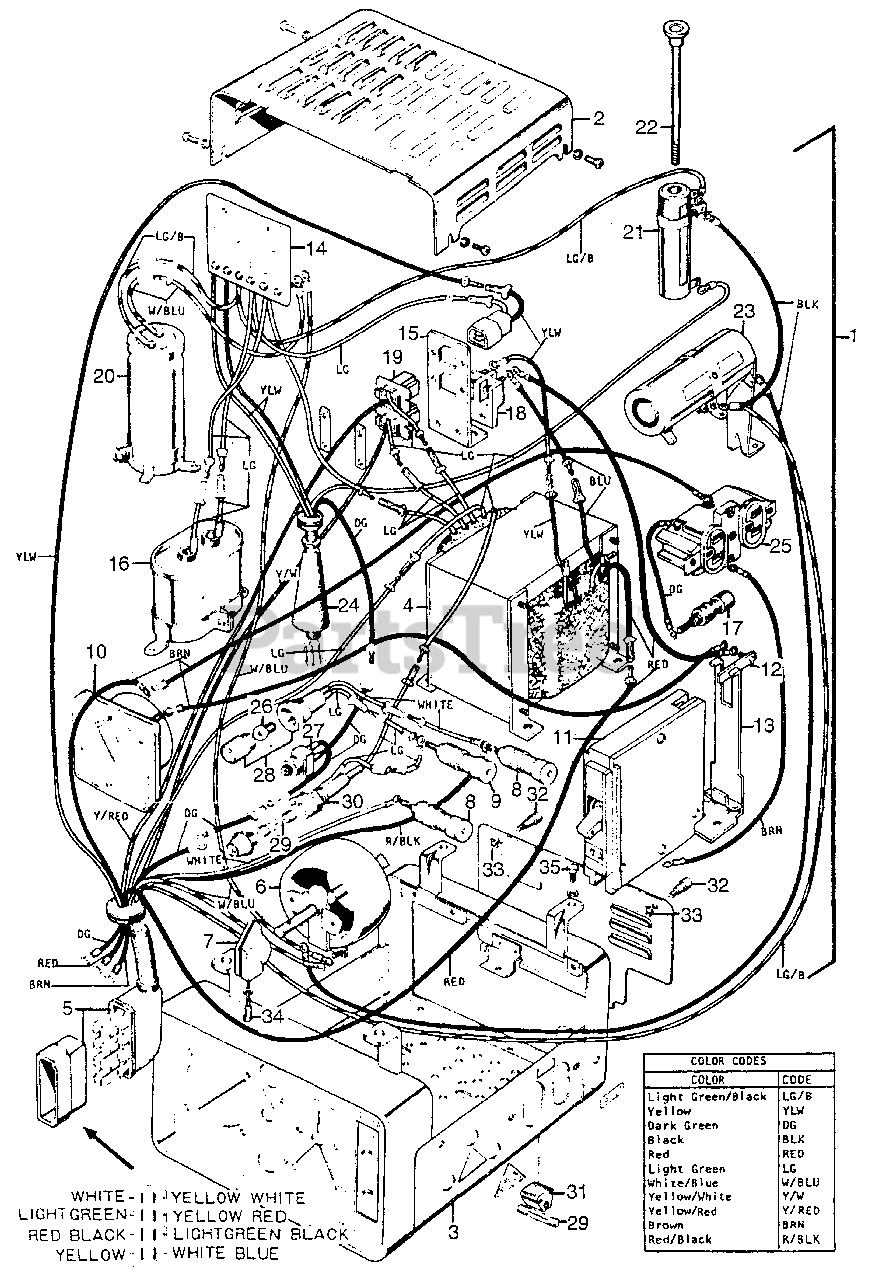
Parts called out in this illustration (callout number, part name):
1	BOX ASSY., CONTROL *R2L* (SCARLET)
2	COVER, CONTROL BOX (UPPER) *R2L* (SCARLET)
3	COVER, CONTROL BOX (LOWER) *R2L* (SCARLET)
4	TRANSFORMER ASSY., CURRENT
5	WIRE HARNESS ASSY. (8P)
6	RESISTOR, VARIABLE
7	KNOB, ADJUSTING
8	TERMINAL, D.C. OUTPUT (+)
9	TERMINAL, D.C. OUTPUT (-)
10	VOLTMETER ASSY. (150V SCALE)
10	VOLTMETER ASSY.
11	BREAKER, CIRCUIT (12.5A) (NOT AVAILABLE)
12	TERMINAL, BREAKER
13	SUPPORT, BREAKER (NOT AVAILABLE)
14	STACK ASSY., DIODE (NOT AVAILABLE)
15	PLATE, CONNECTOR
16	CONDENSER ASSY., B
17	TERMINAL ASSY., GROUND (NOT AVAILABLE)
18	TERMINAL ASSY., FREQUENCY
19	CONNECTOR, FREQUENCY CHANGE (NOT AVAILABLE)
20	CONDENSER ASSY., A
21	RESISTOR, ADJUST (NOT AVAILABLE)
22	BOLT, RESISTOR SET
23	RESISTOR SET
24	WIRE HARNESS ASSY. (4P)
25	RECEPTACLE (15A/125V)
26	BULB, DASH (24V-2W)
27	SWITCH ASSY., ENGINE (NOT AVAILABLE)
28	SOCKET ASSY., PILOT LAMP
30	HOLDER, FUSE (NOT AVAILABLE)
31	SUPPORTER, SPARE FUSE
32	LATCH, SIDE PLATE (NOT AVAILABLE)
33	STOPPER, LATCH (NOT AVAILABLE)
34	BOLT, KNOB
35	BOLT, HEX. (5X8)
